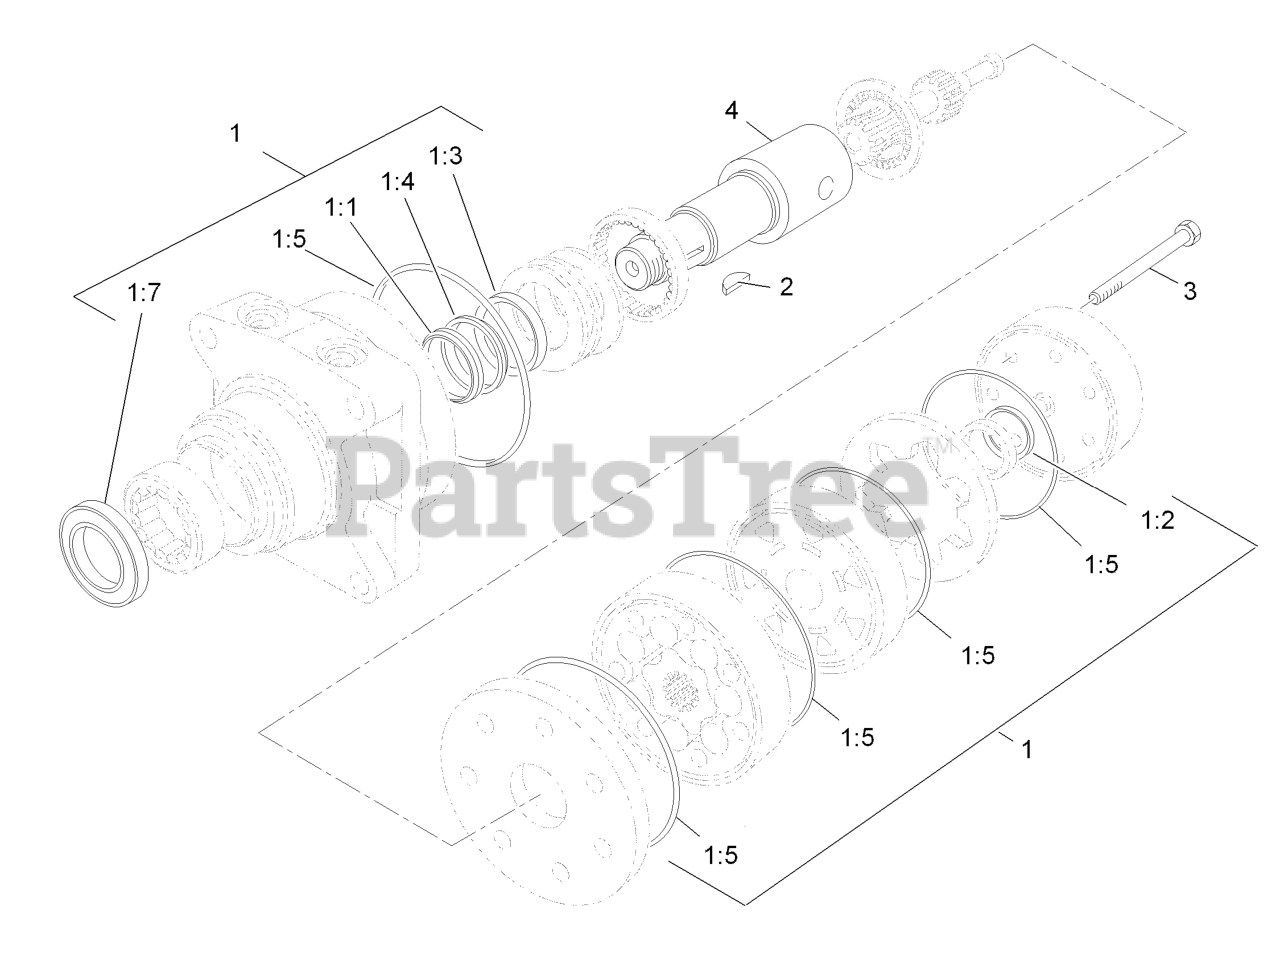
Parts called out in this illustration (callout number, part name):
1	SEAL KIT
1:1	Ring-Back Up
1:2	Seal-Commutator
1:3	Seal-Shaft (Viton)
1:4	Washer-Back Up, Steel
1:5	Ring-Seal (Viton)
1:7	Seal-Dirt And Water
2	KEY-WOODRUFF
3	BOLT-SPECIAL
4	SHAFT-COUPLING
